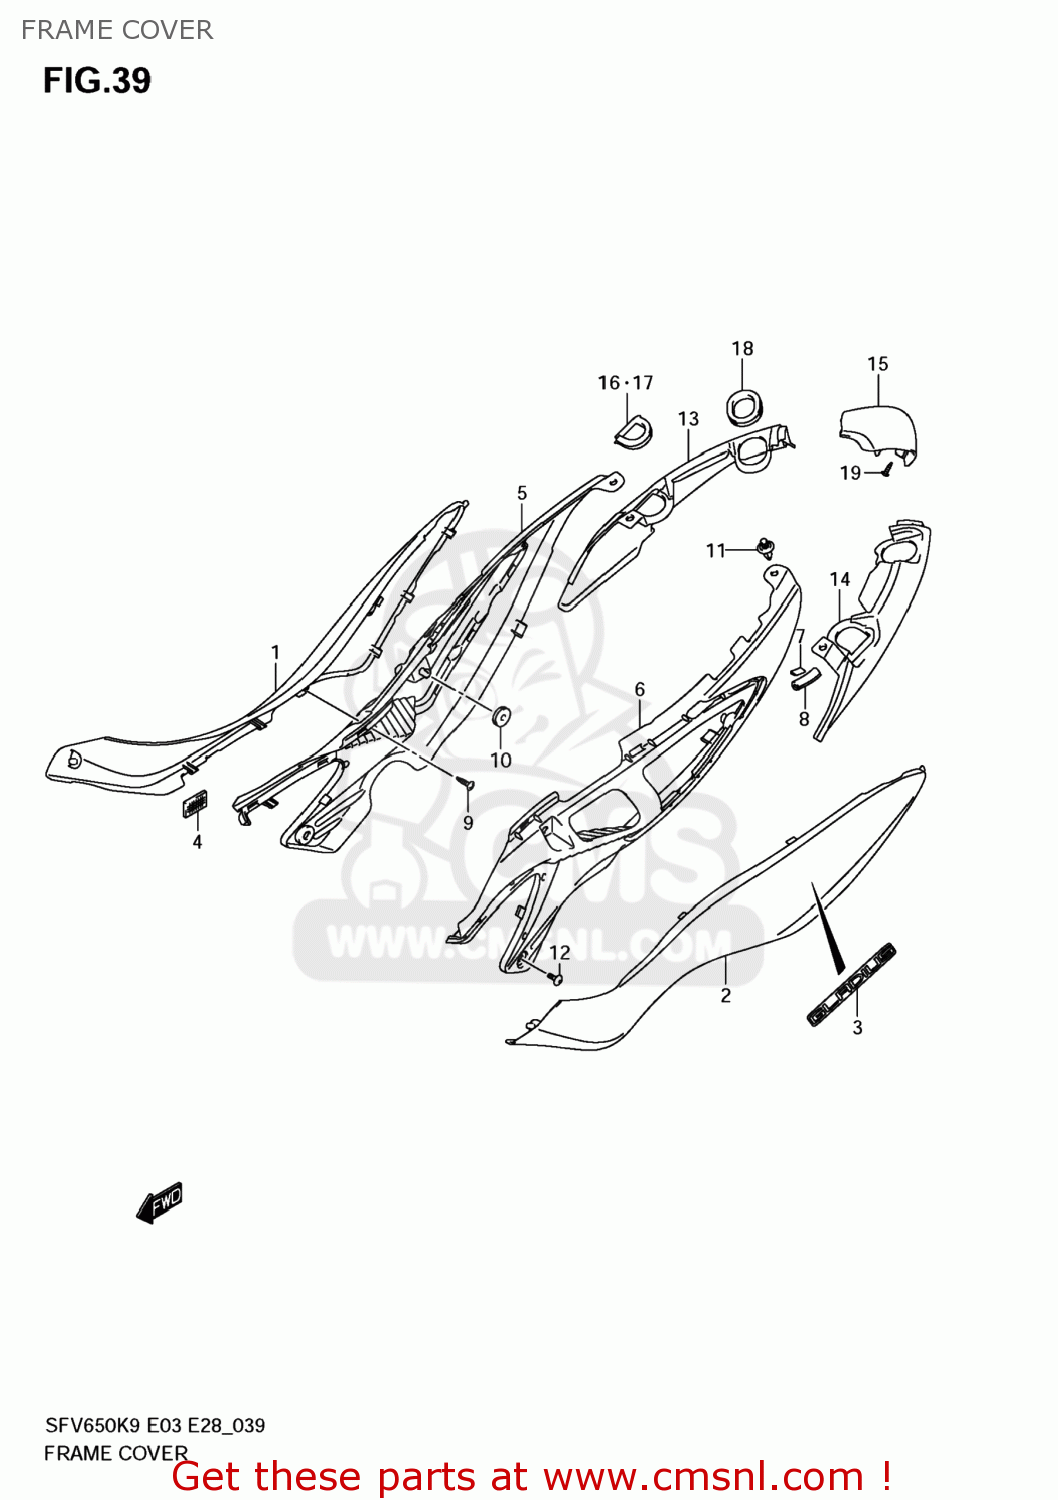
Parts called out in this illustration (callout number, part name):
1	COVER,FRAME,R(WHITE)
2	COVER,FRAME,L(WHITE)
3	EMBLEM,FRAME COVER
4	FASTENER,FRAME COVER
5	COVER,FRAME RR,R
6	COVER,FRAME RR,L
7	TAPE,DRAIN WASHER
8	MOLDING
9	SCREW
10	CUSHION
11	CLIP(BLACK)
12	SCREW(5X13)
13	COVER,FRAME RR CTR,R
14	COVER,FRAME RR CTR
15	COVER,FRAME RR CTR RR
16	CUSHION,COVER RR CTR,R
17	CUSHION,COVER RR CTR,L
18	CUSHION,COVER RR CTR RR
19	SCREW
